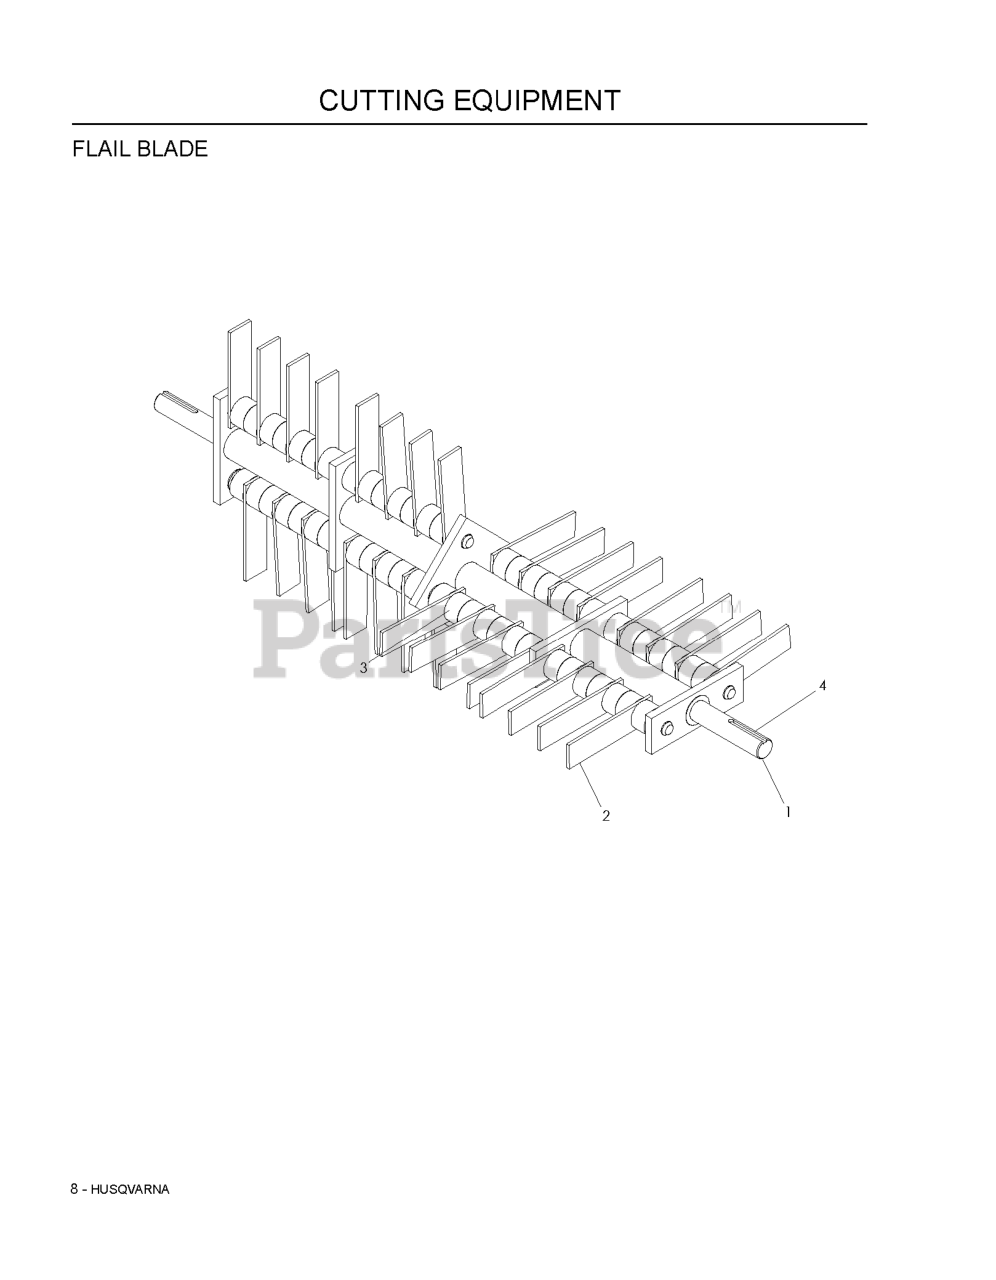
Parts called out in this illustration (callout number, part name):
1	FLAIL ASSEMBLY 18
1	SHAFT WELDED
2	BLADE
2	26 FLAIL SET, SHAFTS, E-RINGS
3	SPACER
4	SHAFT BLADE
